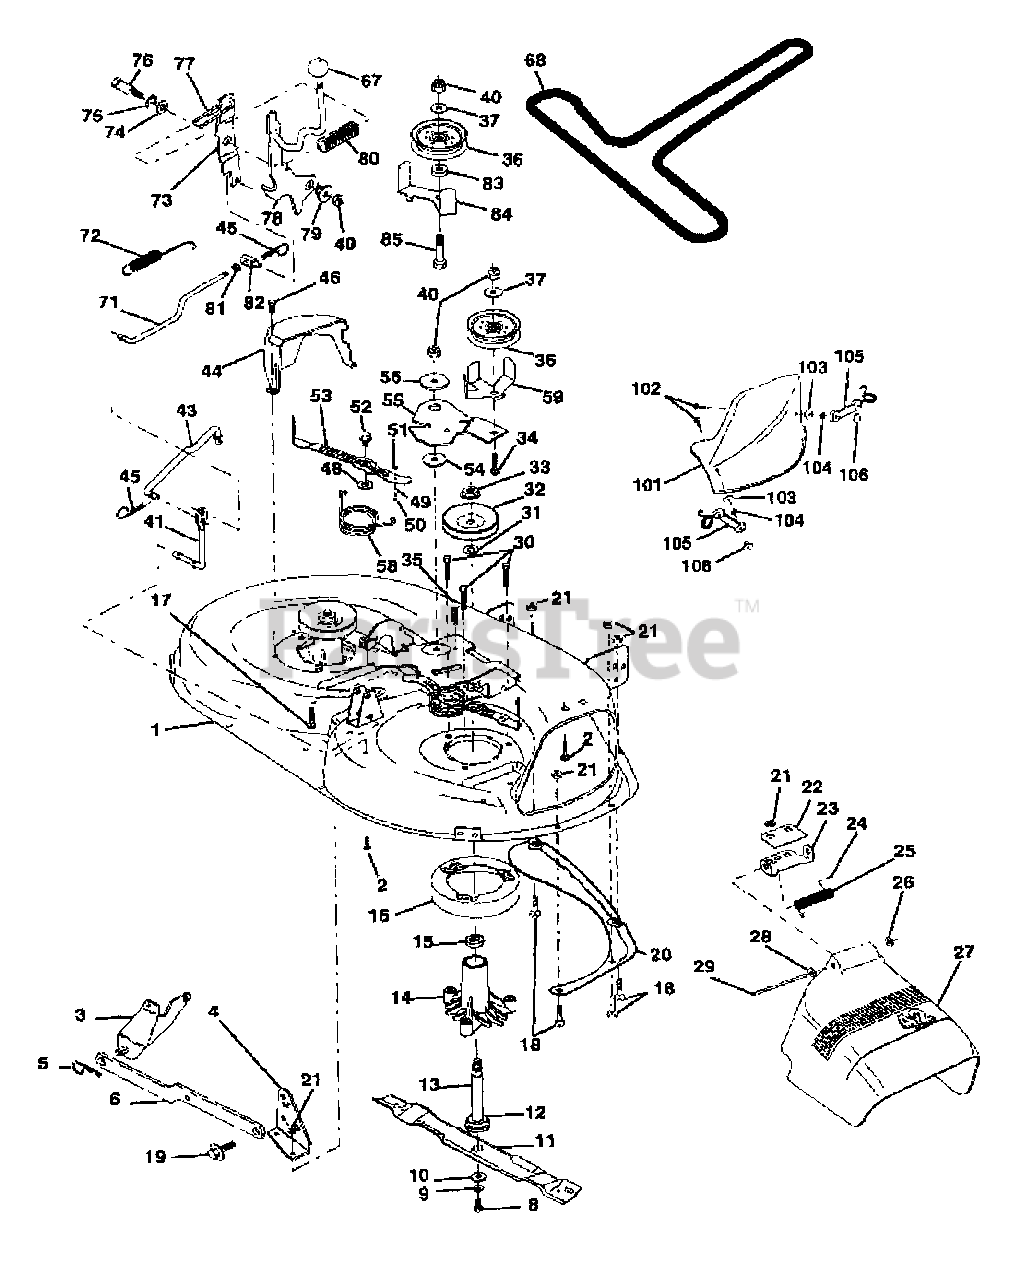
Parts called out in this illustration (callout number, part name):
1	Deck Asm MWR 42" weldment
2	Bolt Rdhd Sqnk 5/16-18unc X3/4
3	Bracket Asm Fr Sway Bar 38/42
4	Bracket Asm Deck 42"sway Bar
5	Retainer Spring
6	Arm Suspension Rear
8	Bolt 3/8 - 24 X 1.25 Gr 8
9	Washer Lock Hvy 3/8
10	Washer Hard Blade Mower Vented
11	Blade Mower Mulching 42"
12	Bearing Ball #6024 (Mandrel)
13	Shaft Asm W/lower Bearing
14	Housing Mandrel Vented
15	Bearing Ball Mandrel
16	Stripper Mower Vented
17	Bolt Rdhd Sqnk 3/8-16 X 1-1/4
18	Bolt Rdhd Sqnk 5/16-18 X 5/8
19	Bolt Shoulder
20	Baffle Vortex 42
21	Nut Crownlock 5/16-18 Unc
22	Stiffener Bracket 42" deck
23	Bracket Deflector Mower 42"
24	Cap Sleeve 80x 112 Blk Mower
25	Spring Torsion Deflector 2 52
26	Nut Push Phos & Oil
27	Shield Deflector Mower 42" Blk
28	Washer 11/32 X 5/8 X 16 Ga
29	Rod Hinge 42" 6 75 Wlg
30	Screw Thdrol Hex Head Zinc Mwr
31	Washer Spacer Mower Vented
32	Pulley Mandrel 42"
33	Nut 9/16 Toplock Flng Oil Dip
34	Bolt Rdhd 3/8-16uncx1-3/4 Gr5
35	Fastener Christmas Tree
36	Pulley Idler Flat 3 060
37	Washer 13/32 X 13/16 X 16
40	Nut Crownlock 3/8-16 Unc
41	Rod Pivot W/nibs
43	Rod Clutch Secondary W/nibs
44	Guard Mandrel LH Black
45	Spring Retainer 1" Zinc/cad
46	Screw Hex Thd Cut 1/4-20x5/8 T
48	Washer Hardened Smaller
49	Roller Asm Cam Follower 42" deck
50	Bolt Shldr 10-24 Zinc Gr 5 42"
51	Nut Lock #10-24 Unc
52	Bolt Shoulder 5/16-18 Unc Blkz
53	Arm Asm Pad Brake
54	Washer Hardened
55	Arm Idler 42" mower LT/YT
56	Spacer Retainer Pm Mower
58	Spring Torsion Brakes
59	Guard TUV Idler
67	Knob Rd 1/2-13 Plstc Thds Blk
68	V-Belt Mower 42"
71	Rod Clutch Primary 38/42
72	Spring Return
73	Arm Clutch Secondary
74	Washer 25/32 X 1-5/8 X 16 Ga
75	Ring Klip #t5304-75
76	Bolt Shoulder 3/8-16 Unc 1 44
77	Keeper Spring 4 000
78	Arm Asm Clutch Primary
79	Bushing 747 Od X 794 Lg Brass
80	Spring Clutch Mower 2 750 Zinc
81	Nut Hex Jam 3/8-16
82	Trunnion Adj 94
83	Washer Sintered
84	Keeper Belt Idler Fixed
85	Bolt Carriage 3/8-16 x 2-1/2 Gr. 5
101	Cover Mulching 42" Black
102	Screw
103	Washer #10
104	Washer Lock #10
105	Latch Asm Bagger
106	Nut Weld
